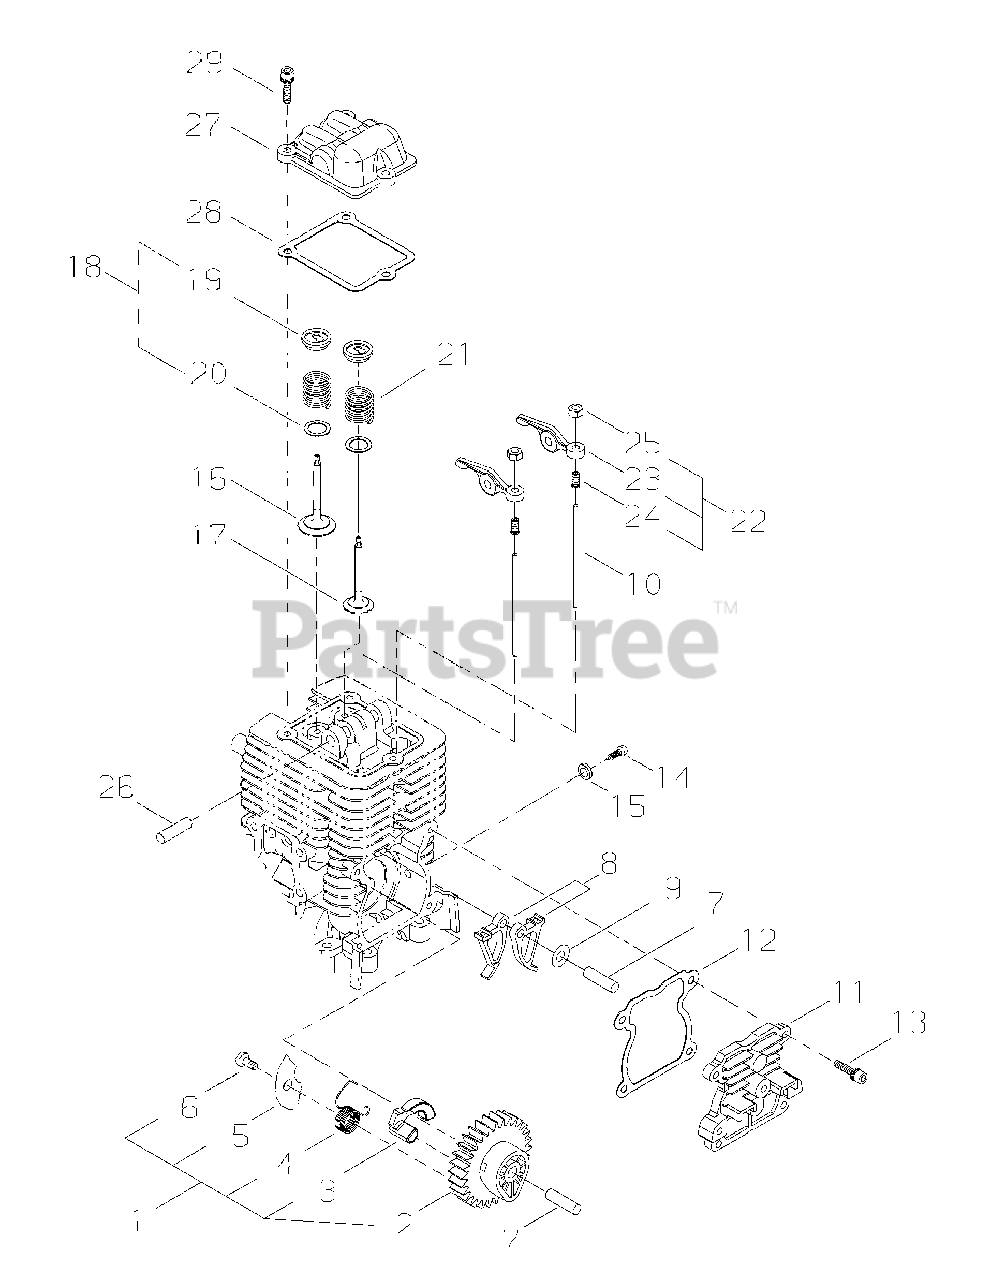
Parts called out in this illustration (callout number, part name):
1	CAM GEAR ASSY
2	GEAR, CAM
3	WEIGHT
4	SPRING
5	PLATE, COVER
6	SCREW, TAPPING 4×6
7	PIN, LOCATING Ø5×29.8 MM
8	FOLLOWER, CAM
9	WASHER 5 MM
10	PUSHROD
11	COVER, CAM GEAR
12	GASKET, CAM GEAR
13	BOLT M4×14
14	SCREW M5
15	WASHER Ø10ר5.5×2
16	VALVE, INTAKE
17	VALVE, EXHAUST
18	RETAINER SET, VALVE
19	RETAINER, VALVE
20	WASHER, VALVE 9
21	SPRING, VALVE
22	ARM ASSY, ROCKER
23	ARM, ROCKER
24	SCREW, ADJUSTER
25	NUT, ADJUSTER LOCK 5
26	SHAFT, ROCKER ARM Ø5×37.8 MM
27	COVER, ROCKER ARM
28	GASKET, ROCKER ARM
29	BOLT M4×14
